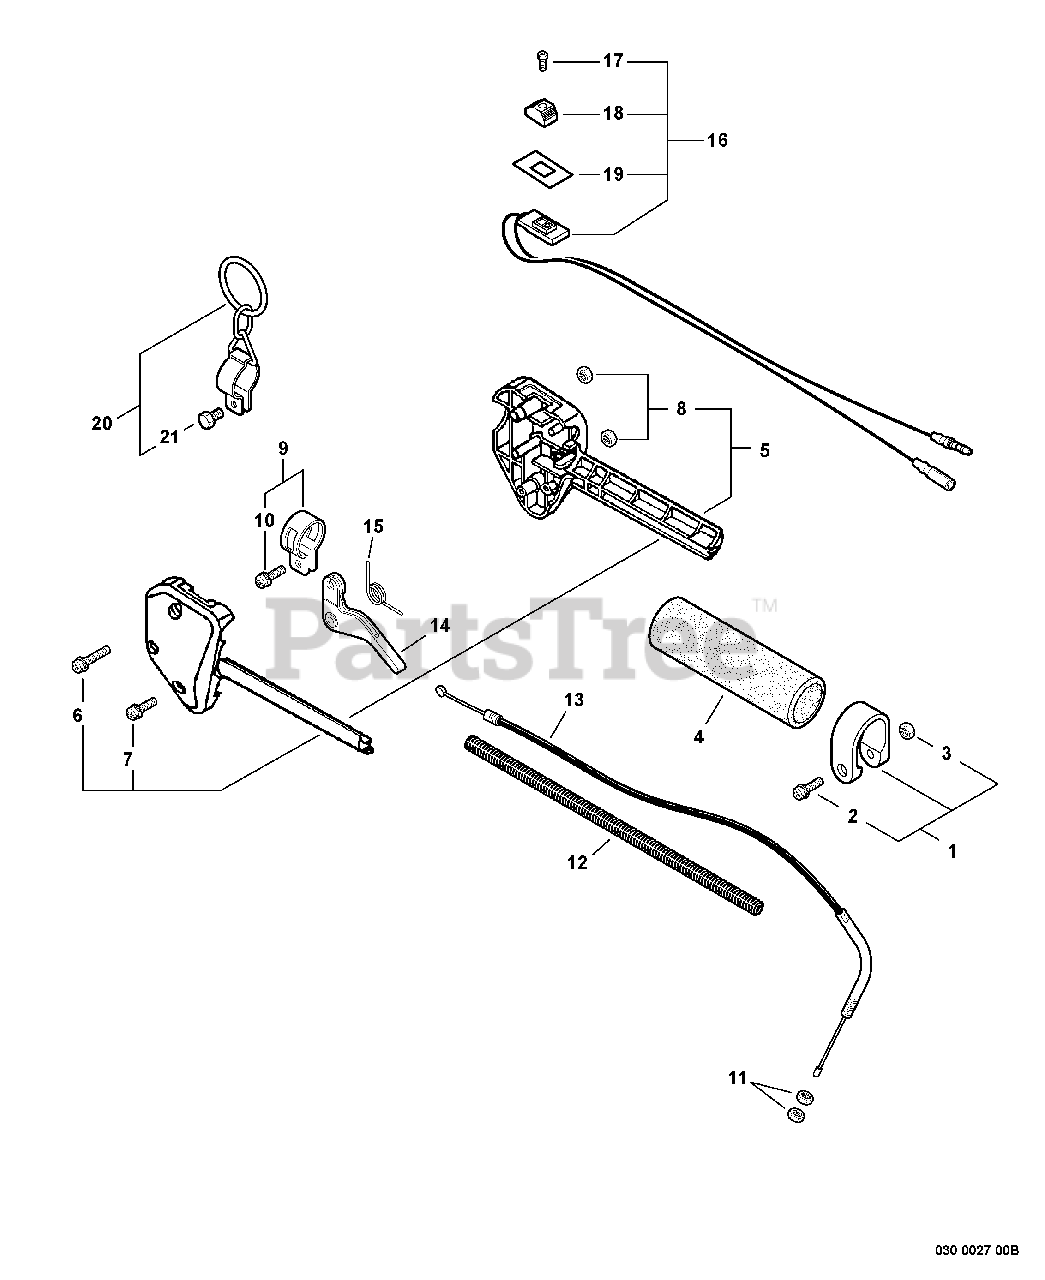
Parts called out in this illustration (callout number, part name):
1	CLAMP KIT
2	SCREW 5×28
3	NUT M5
4	GRIP, HANDLE
5	HANDLE KIT, CONTROL
6	SCREW 5×35
7	SCREW 5×25
8	NUT M5
9	CLAMP KIT
10	SCREW 5×14
12	TUBE, FLEXIBLE
13	CABLE, THROTTLE
14	TRIGGER, THROTTLE
15	SPRING, TORSION
16	SWITCH, ON-OFF
17	SCREW 3×10
18	KNOB, SWITCH - ORANGE
19	LABEL, SWITCH
20	HANGER SET, HARNESS
21	BOLT 5×12
